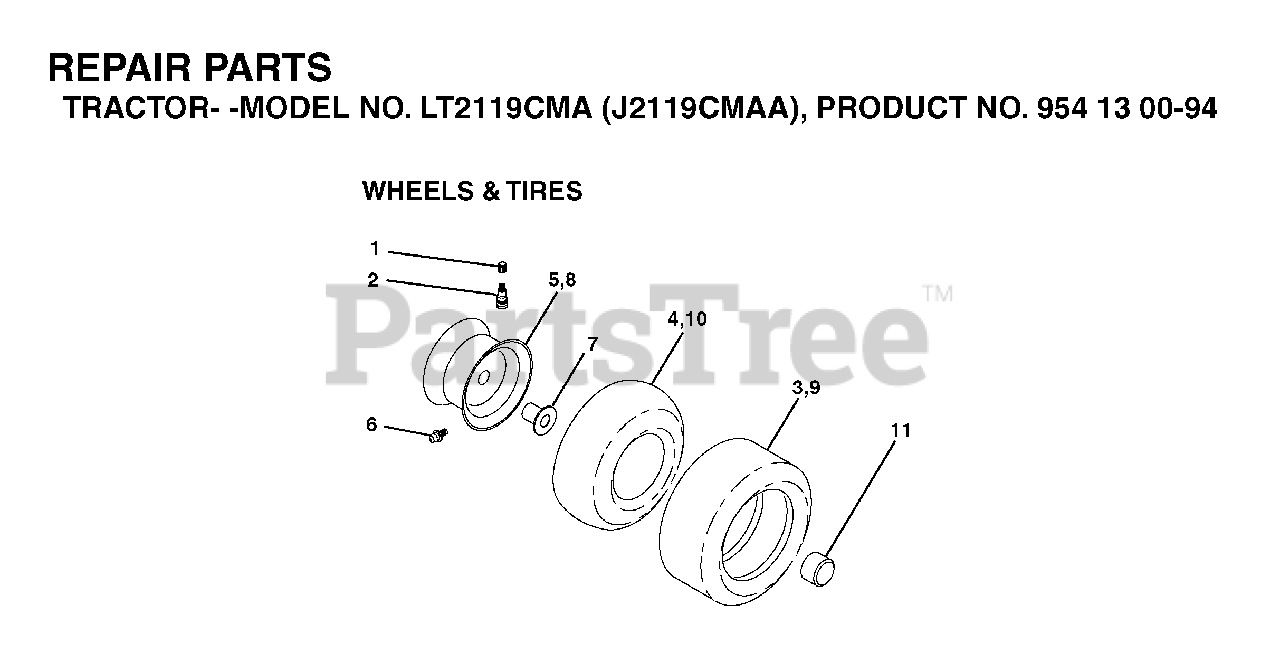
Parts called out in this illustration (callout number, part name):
1	VALVE CAP
2	VALVE STEM LT
3	TIRE HEAVY DUTY
4	TUBE.5.3/4.5/6
5	RIM ASM 6" FRONT SILVER
6	FITTING LT
7	BEARING T
8	RIM ASM 8" REAR SILVER
9	TIRE 20X8-8 TURF SAVER
10	TUBE
11	CAP, AXLE BLK
